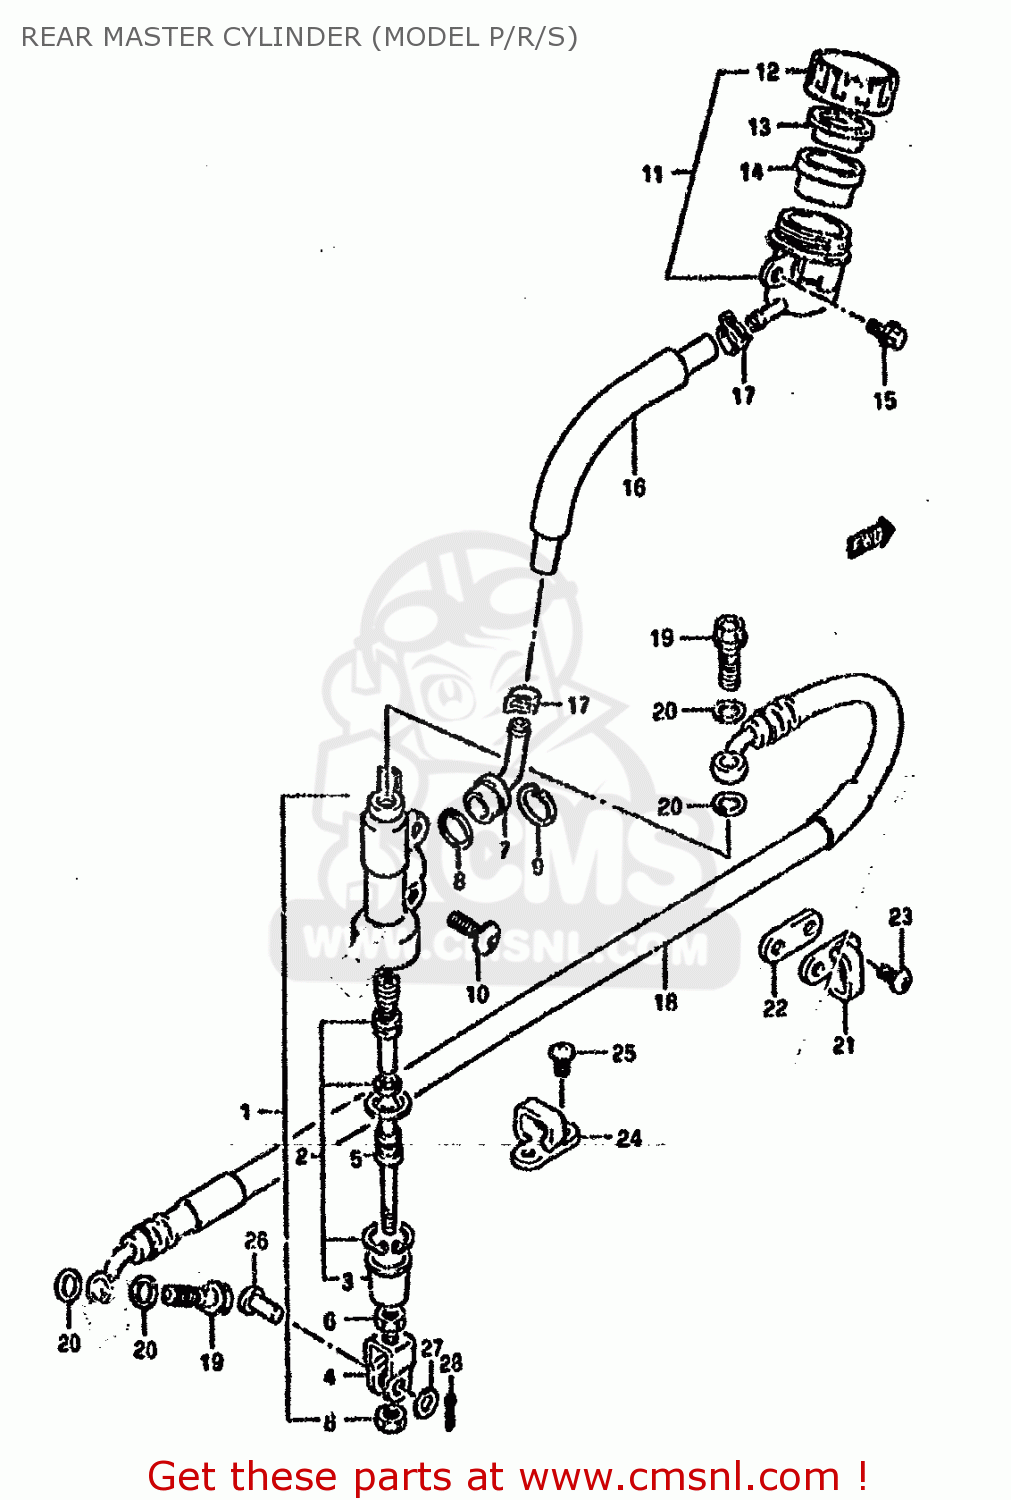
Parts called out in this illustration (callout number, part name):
1	CYLINDER ASSY,RR MASTER
2	PISTON/CUP SET
3	BOOT
4	YOKE
5	ROD,PUSH
6	NUT
7	CONNECTOR
8	O RING
9	CIRCLIP
10	SCREW(6X16)
11	TANK ASSY,RR BRAKE RESERVOIR
12	CAP
13	PLATE
14	DIAPHRAGM
15	BOLT
16	HOSE,TANK
17	CLAMP,RESERVOIR HOSE
18	HOSE,REAR BRAKE
19	BOLT UNION
20	WASHER(10X15X1.5)
21	GUIDE,RR BRAKE HOSE
22	SEAT,RR BRAKE HOSE GUIDE
23	SCREW
24	GUIDE,RR BRAKE HOSE
25	SCREW
26	PIN(8X20)
27	WASHER(8.5X13X1.6)
28	PIN
